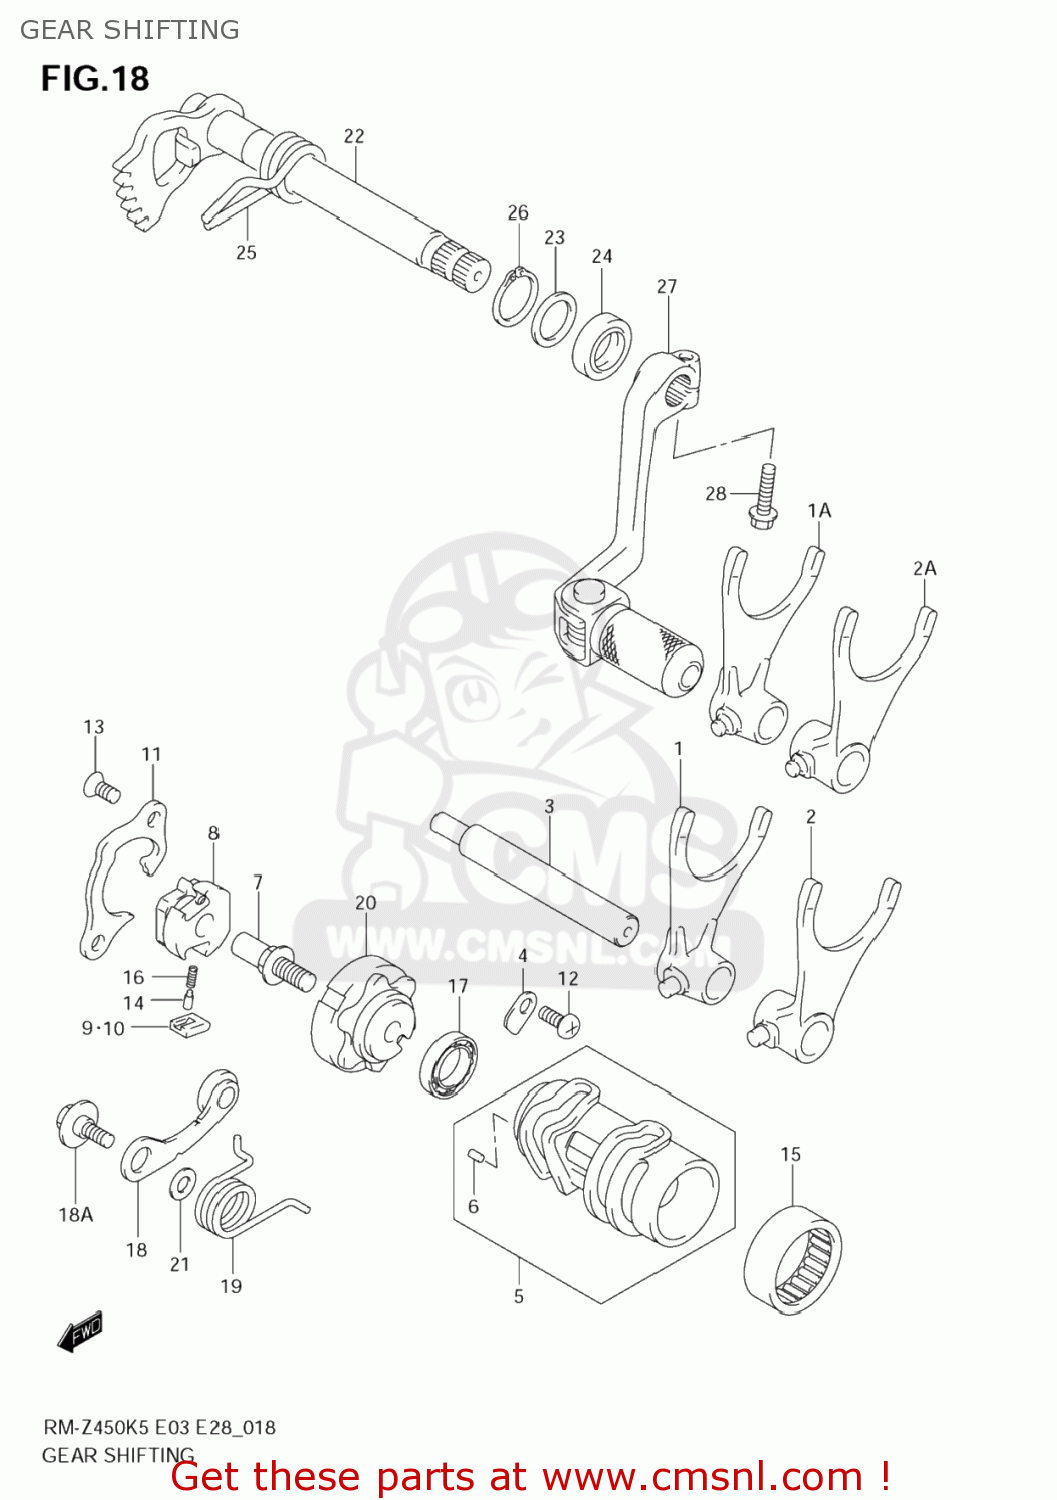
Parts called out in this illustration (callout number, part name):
1	FORK,GEAR SHIFT NO.1
1A	FORK,GEAR SHIFT NO.1
2	FORK,GEAR SHIFT NO.2
2A	FORK,GEAR SHIFT NO.2
3	SHAFT,GEAR SHIFT FORK NO.1
4	RETAINER
5	CAM,GEAR SHIFT
6	PIN
7	PIN,SHIFT CAM DRIVEN GEAR
8	GEAR,GEAR SHIFT CAM DRIVEN
9	PAWL,GEAR SHIFT NO.1
10	PAWL,GEAR SHIFT NO.2
11	LIFTER,GEAR SHIFT PAWL
12	BOLT(6X12)
13	SCREW(6X12)
14	PIN
15	BEARING(33X38X8)
16	SPRING
17	BEARING
18	STOPPER,GEAR SHIFT CAM
18A	BOLT(6X14.3)
19	SPRING,GEAR SHIFT CAM
20	PLATE,SHIFT CAM STOPPER
21	WASHER
22	SHAFT,GEAR SHIFT
23	SHIM(14X20X1)
24	SEAL,OIL(14X22X6)
25	SPRING
26	CIRCLIP
27	LEVER ASSY,GEAR SHIFT
28	BOLT,6X20
